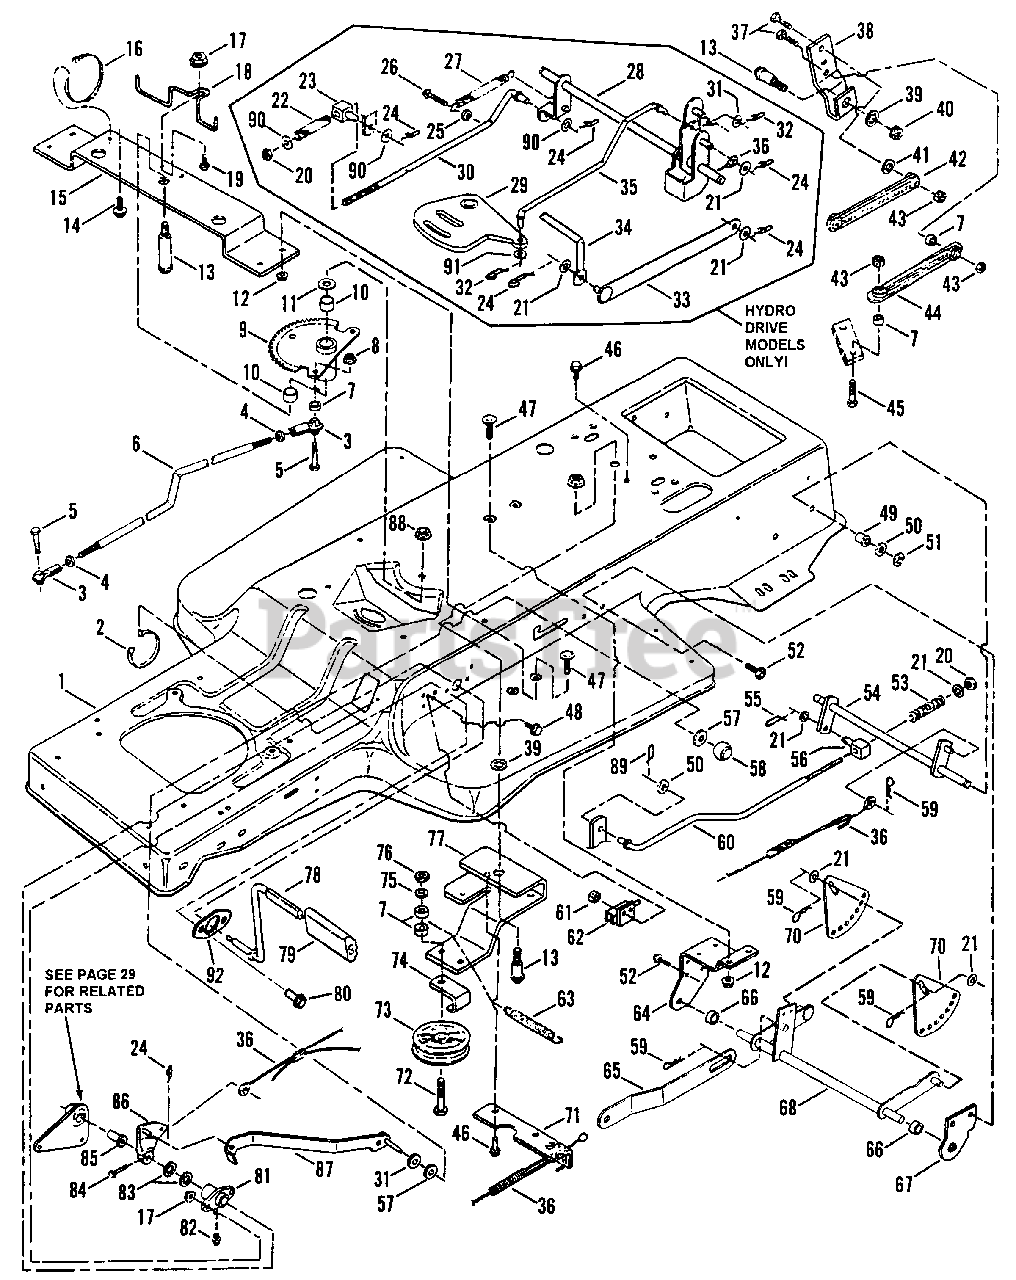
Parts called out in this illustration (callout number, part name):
1	FRAME, Tractor
2	TIE, Wire
3	BALL JOINT, 3/8-24
4	NUT, 3/8-24 Hex Jam
5	SCREW, 3/8-24 x 1 1/4" Hex Head Cap
6	LINK, Drag
7	SPACER
8	NUT, 3/8-16 Hex Flange Lock
9	ASSEMBLY, Sector Gear
10	BEARING, Sector Gear
11	WASHER, 3/4 Thrust
12	NUT, 1/4-20 Hex Flange Lock
13	BOLT, 1/2-13 x 2" Hex Flng. Lk.
14	SCREW, #10-24 x 1/2" Hex Washer Self-Tap (Torx)
15	BRACE, Sector Gear
16	TIE, Cable
17	NUT, 5/16-18 Hex Flange Lock
18	GUIDE, Drive Belt
19	BOLT, 5/16-18 x 3/4" Hex Flng. Lk.
20	NUT, 3/8-16 Hex Nyloc
21	WASHER, 3/8" Flat
22	SPRING, Brake
23	SWIVEL, Inline Brake
24	PIN, 3/64 x 1 7/32" Cotter (Self-Lkg.)
25	NUT, 5/16-18 Hex Center Lock
26	SCREW, 5/16-18 x 1-1/4" Self-Tapp.
27	SPRING
28	WELDMENT, Brake Arm
29	ARM, Transmission Speed Control
30	ROD, Brake
31	WASHER, 5/16 Flat
32	PIN, 5/16 Cotter, Self-Locking
33	LINK, Shift
34	ASSEMBLY, Shift Lever (Lower)
35	LINK, Speed
36	ASSEMBLY, Clutch/Brake Cable
37	SCREW, 3/8-16 x 1-1/4" H. H. C.
38	BELLCRANK, Shift Lever
39	WASHER, 1/2 Internal Tooth Lk.
40	NUT, 1/2-13 Hex Flange Lock
41	WASHER, 3/8 Split Lock
42	LINK, Shift Lever
43	NUT, 3/8-16 Hex Center Lock
44	LINK, Shift Lever (Twisted)
45	SCREW, 3/8-16 x 1-1/2" H. H. C.
46	SCREW, 5/16-18 x 5/8" Self-Tap
47	BOLT, 1/4-20 x 5/8" Carriage
48	SCREW, #10-32 x 5/8" H. W. H.
49	BEARING, Nylon
50	WASHER. 1/2 Flat
51	RING, 1/2" External Retaining
52	SCREW, 5/16-18 x 5/8" Truss Head (Torx)
53	SPRING, Brake
54	WELDMENT, Brake Pivot
55	COTTER-PIN, 1/16" x 1.42" Self-Locking
56	SWIVEL, Brake Link
57	WASHER, 5/16 Nylon
58	KNOB, Push/Pull
59	PIN, 3/32 x 1-1/2" Hair
60	ROD, Brake
61	NUT, #10-32 Hex Nyloc
62	SWITCH
63	SPRING
64	BRACKET, Rear Lift/PTO Lever
65	LINK, Lift
67	BRACKET, Deck Hang Pivot
68	WELDMENT, Rear Lift
70	PLATE, Lift Sector
71	EXTENSION, Idler Arm
72	SCREW, 3/8-16 x 2-1/4" Hex Head Cap
73	PULLEY
74	GUIDE, Pulley
75	WASHER, 3/8 Split Lock
76	NUT, 3/8-16 Hex
77	ARM, Idler (Traction Drive)
78	PEDAL, Park Brake
79	PAD, Pedal
80	SCREW, 3/8-16 x 7/8" Truss Head (Torx)
81	ASSEMBLY, Foot Shaft Pivot
82	FITTING, Lube
83	WASHER, 5/8 Flat
84	PIN, 3/16 x 1-1/2" Clevis
85	BEARING, Flange
86	ASSEMBLY, Clutch Brake Arm
87	LATCH, Park Brake
88	NUT, 1/2-13 Hex Center Lock
89	PIN, 1/16 x 1-27/64 Cotter (Self Locking)
90	WASHER, 3/8" Flat
91	WASHER, .06 x .34 I.D. x .69" O.D., Grade 5
92	WASHER, Pivot- Stiffener
